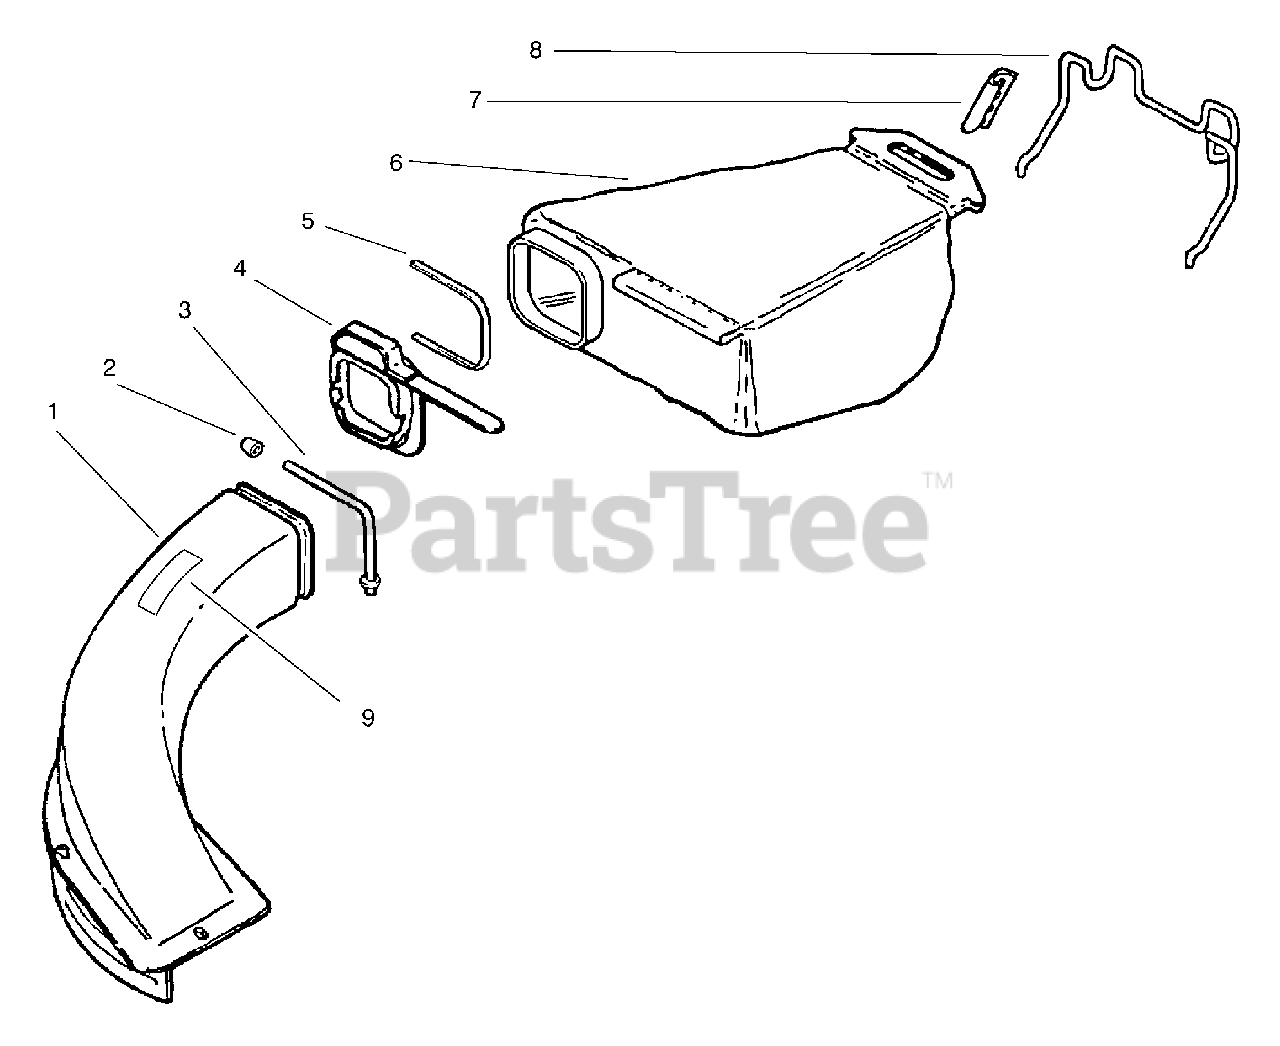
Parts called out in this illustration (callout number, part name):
1	ASM-Chute & Support
2	Nut-Cap
3	Support-Chute
4	ASM-Adaptor
5	Tie Strap
6	ASM-Bag & Adapter
7	Hanger-Clamp
8	Hanger-Wire
9	Decal-Danger
